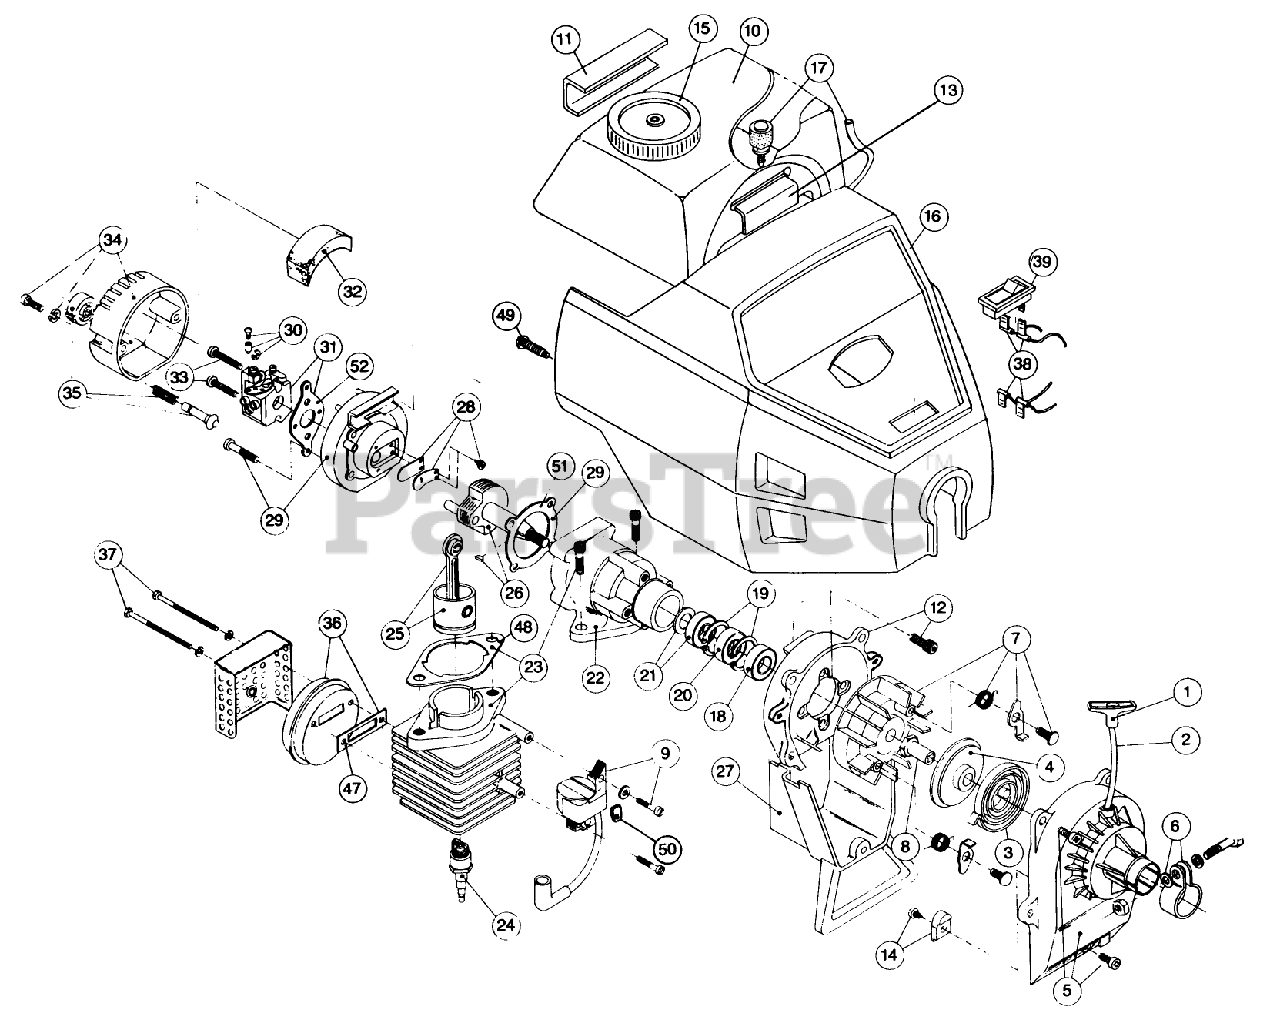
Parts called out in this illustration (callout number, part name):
8	SQUARE DRIVE NUT
12	SHROUD ASM
13	FRONT MOUNTING PAD
17	FUEL LINE ASM
18	OUTER BEARING
20	SEAL
21	INNER BEARING ASM
24	SPARK PLUG
30	THROTTLE ADJ ASM
37	MUFFLER MOUNTING BOLTS
45	SHORT BLOCK ASM
52	CARB.GASKET
56	FLYWHEEL KEY (10-PK)
